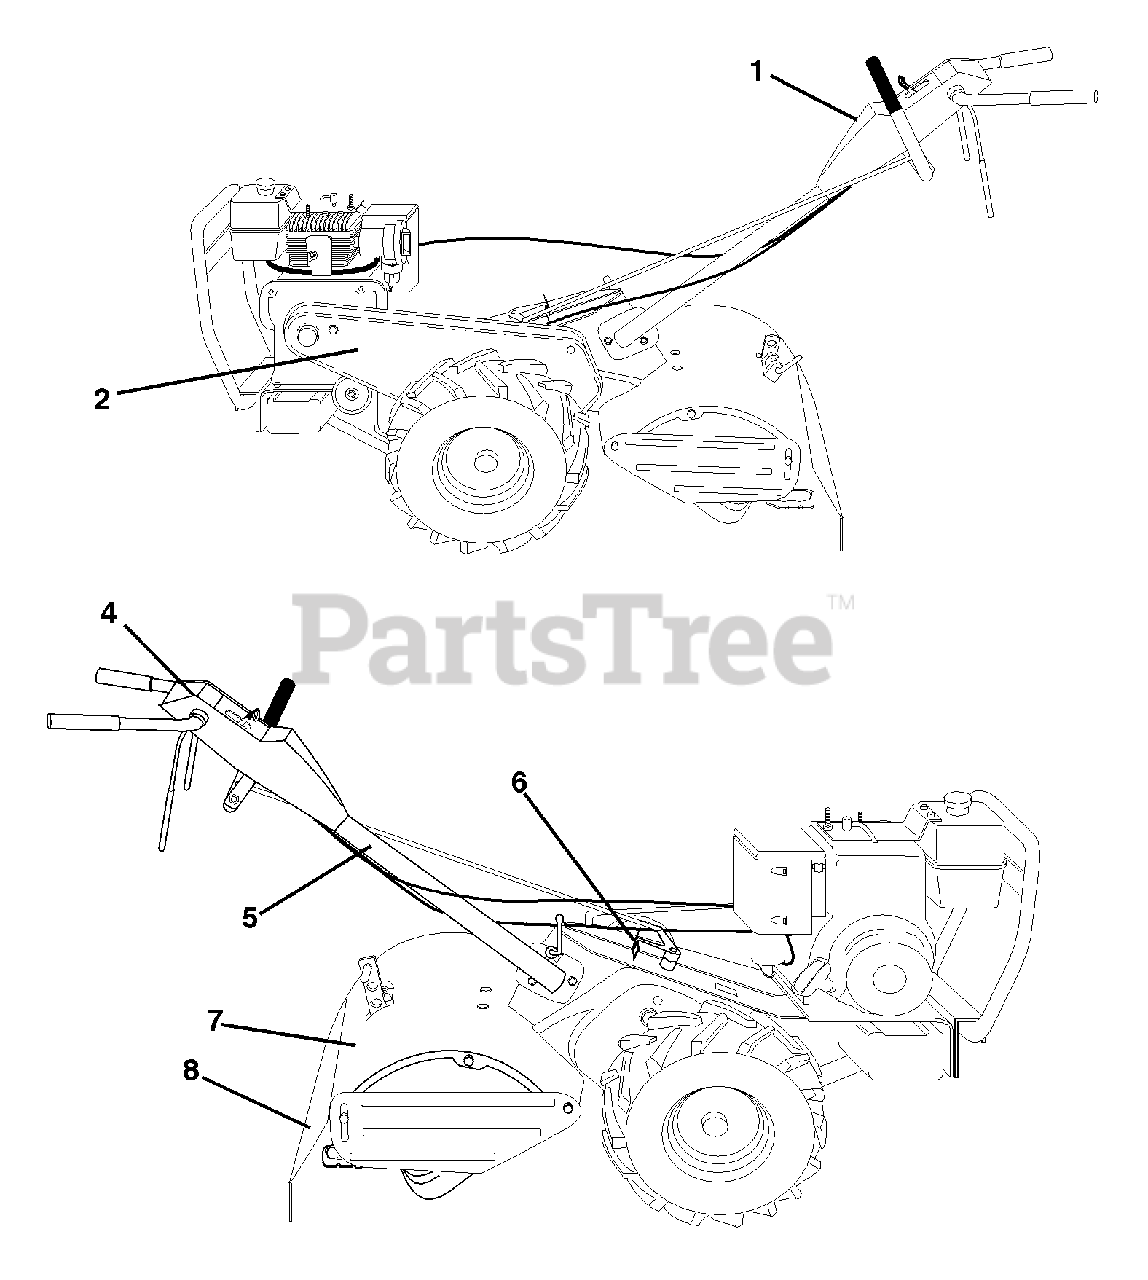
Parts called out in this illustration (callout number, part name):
1	Decal, Logo
2	Decal, Logo
4	Decal, Instruction, Tilling
5	Decal, Hand Placement
6	Decal, Shift Indicator
7	Decal, Caution
8	Decal, Warning, Rotating Tines
